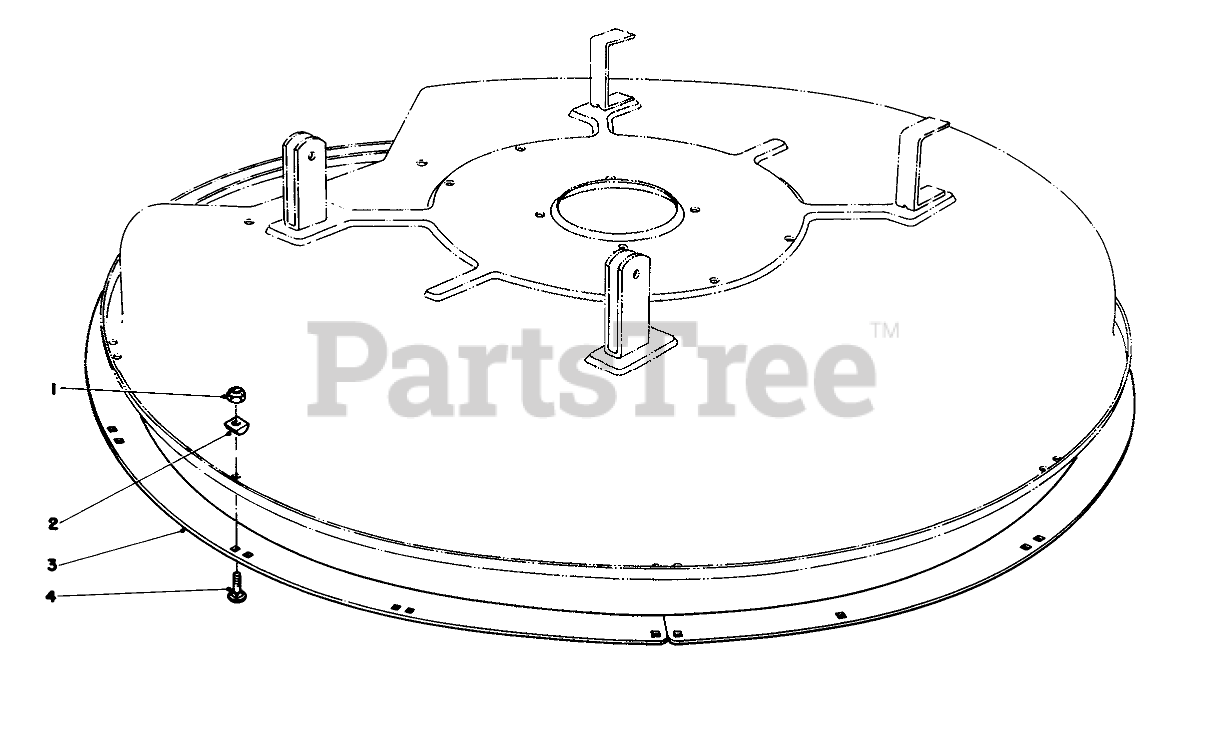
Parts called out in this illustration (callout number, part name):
1	NUT-LOCK, NI
2	DECK RING SPACER
3	DECK RING B
4	BOLT-CARR
